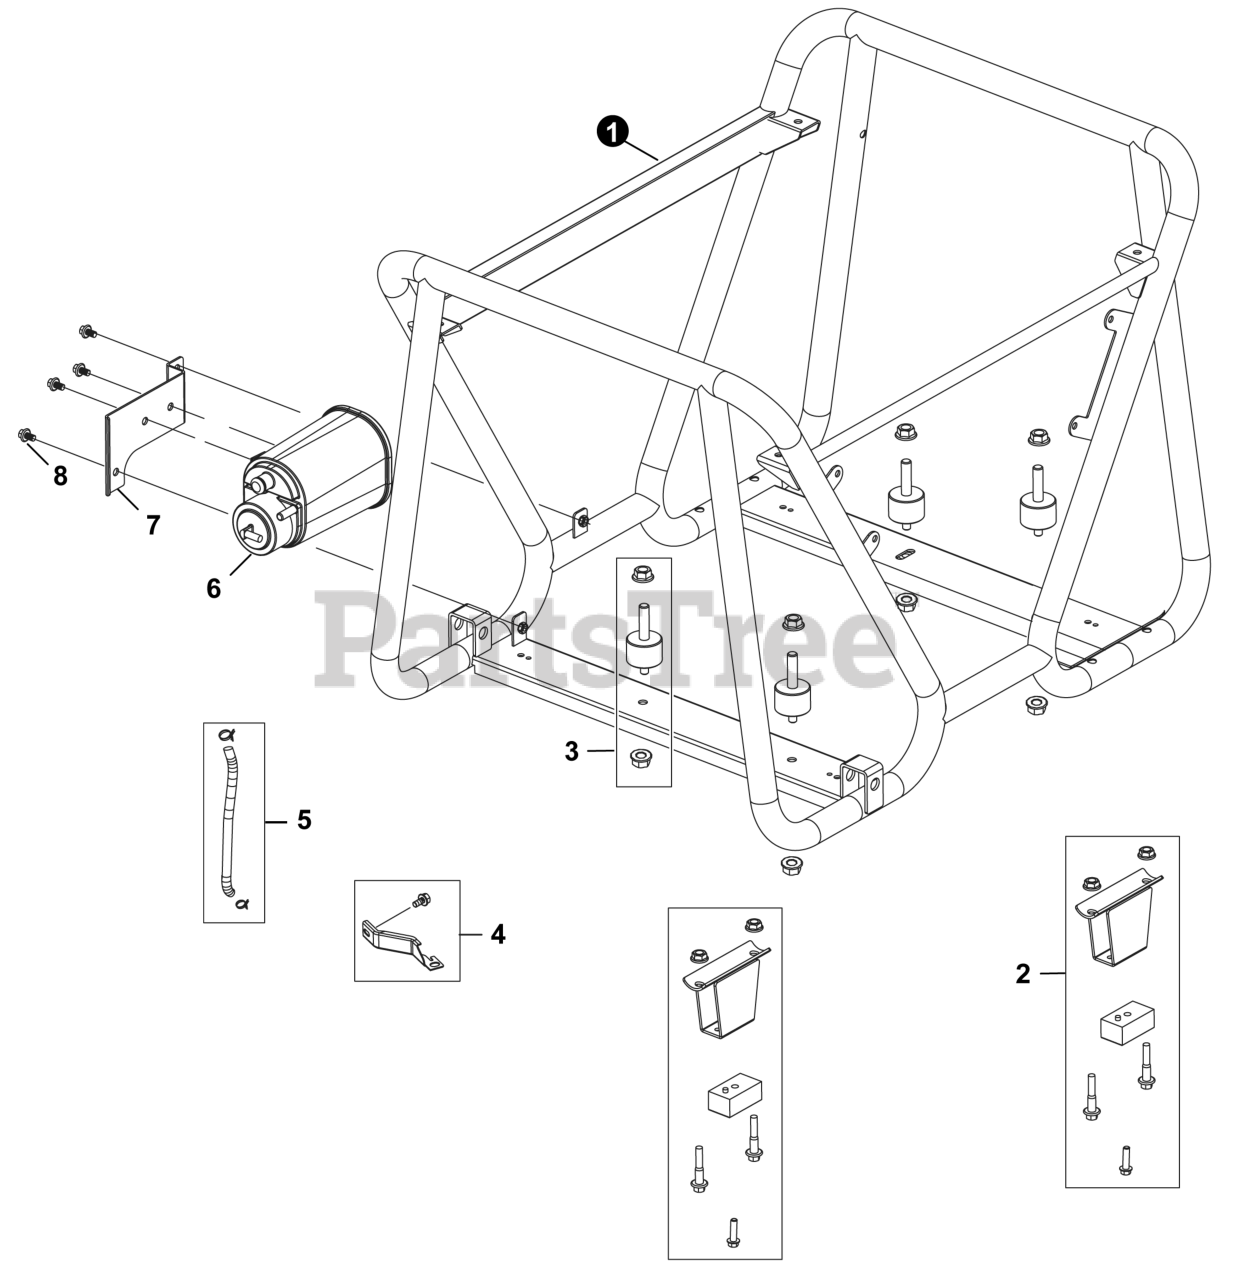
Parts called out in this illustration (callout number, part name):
1	FRAME ASSY, ENGINE
2	MOUNT, ENGINE
3	CUSHION, ENGINE FRAME
4	SUPPORT, ATR CLEANER
5	HOSE ASSY., FUEL
6	CANNISTER, VAPOR
7	PLATE, FUEL STEAM
